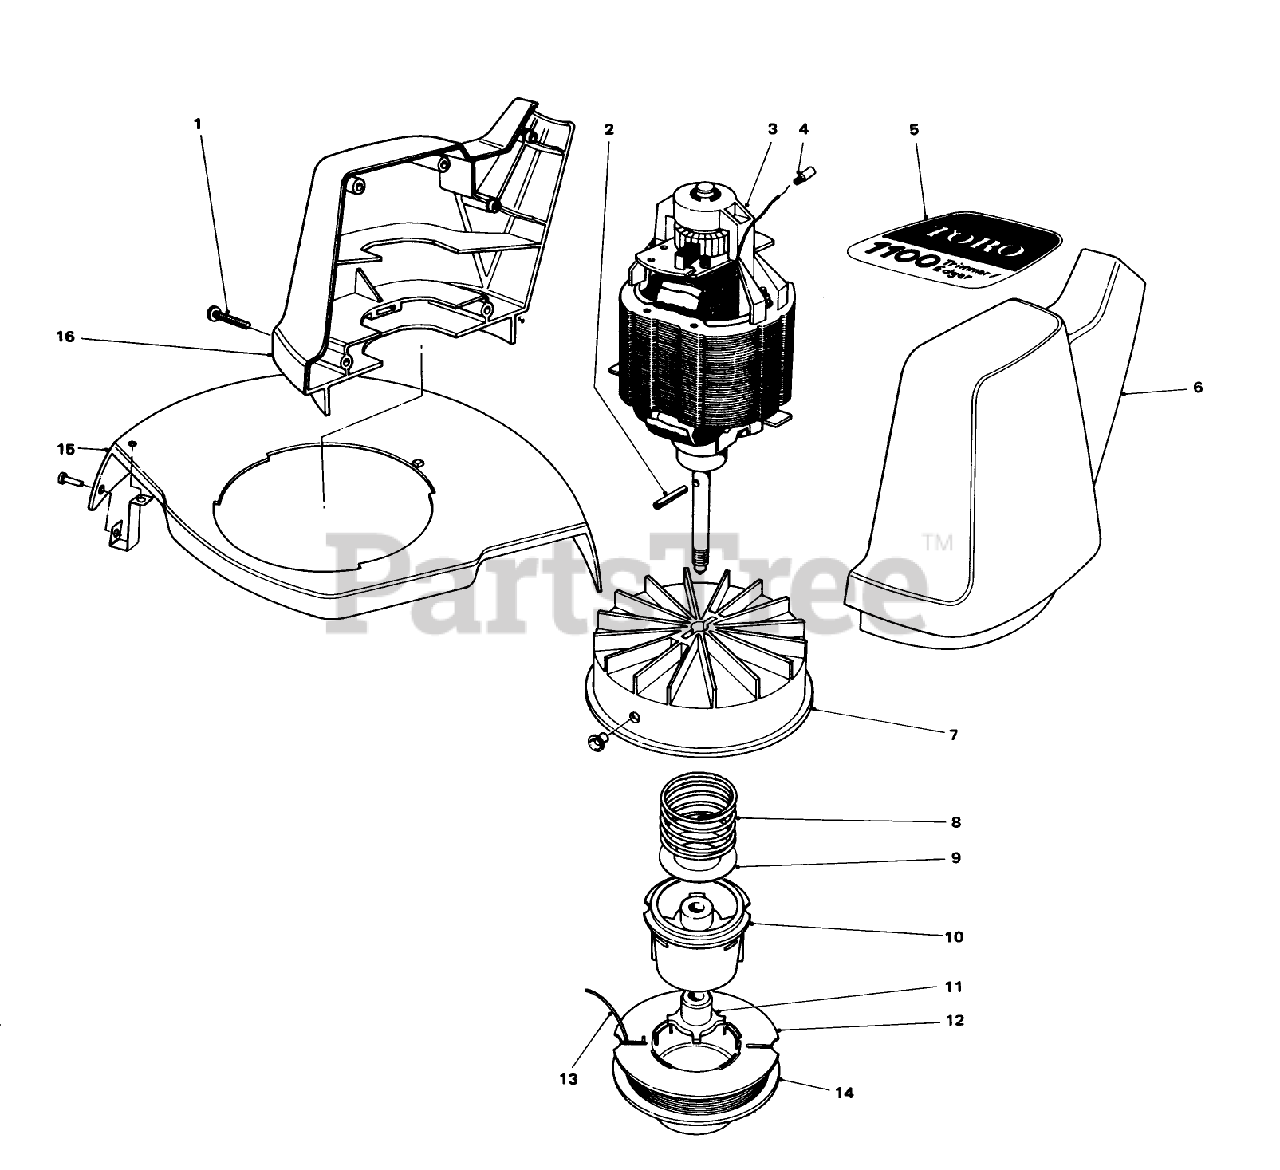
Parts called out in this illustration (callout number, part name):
1	SCREW-PPH
2	COIL PIN
3	Motor
4	CONNECTOR WIRE JOINT
5	Toro 1100 Decal
6	Left Motor Housing
7	Fan Hub with Eyelet
8	SPRING COMPRESSION
9	WASHER-FLAT
10	Spool Core
11	Driver
12	Empty SPooI
13	50-Coil.065" Cutting Line
14	Prewound Spool
15	Shield with Cut Off Blade
16	Right Motor Housing
